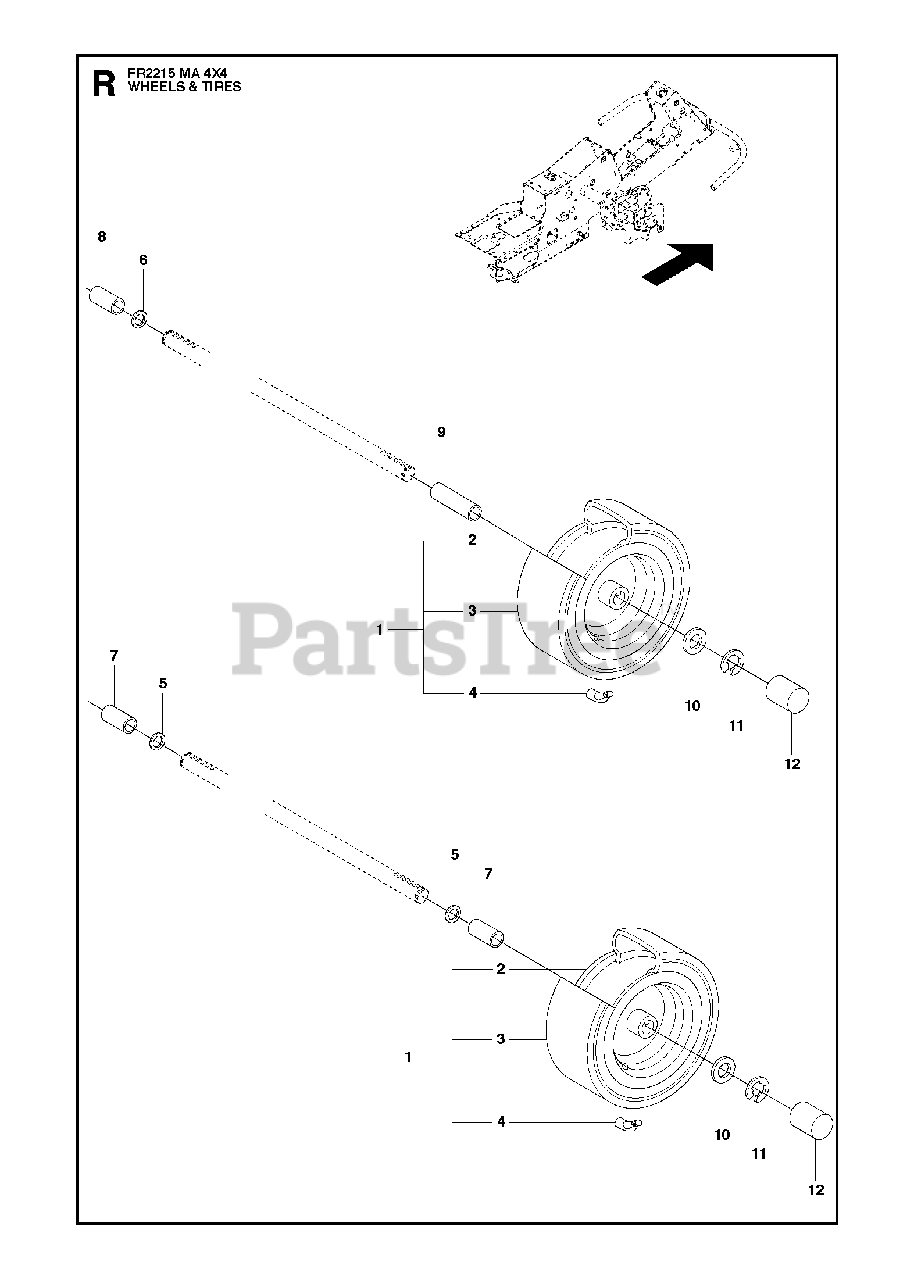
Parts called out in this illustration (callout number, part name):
2	RIM
7	SPACE SLEEVE
11	RETAINING RING
